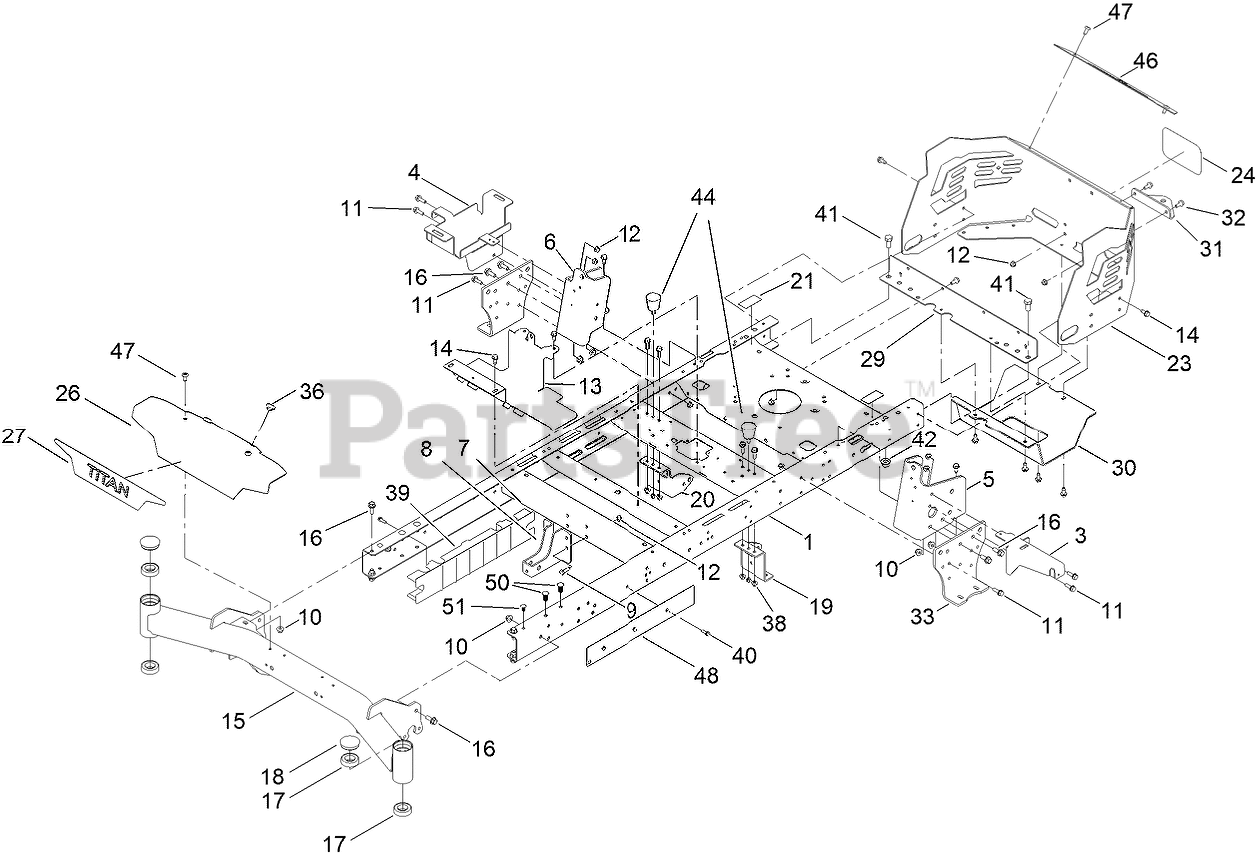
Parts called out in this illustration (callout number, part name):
1	FRAME ASM
3	BRACKET-SUPPORT, POD (LH)
4	TRAY-BATTERY
5	BRACKET-MOUNTING, LH
6	BRACKET-MOUNTING, RH
7	BRACE-CROSS, LOWER
8	BRACKET-MOUNT DAMPER, LOWER
9	SCREW-HH
10	NUT-HF, NI
11	SCREW-HHF
12	NUT-HF
13	BRACKET-MOUNT
14	SCREW-HWHTF
15	FRONT AXLE ASM
16	SCREW-HHF
17	BEARING-BALL
18	CAP-GREASE
19	MOUNT-HYDRO, FRONT (LEFT)
20	MOUNT-HYDRO, FRONT (RIGHT)
21	DECAL-BYPASS
23	GUARD-ENGINE
24	DECAL
26	PLATE-FRONT
27	DECAL-TITAN
29	CROSSMEMBER-REAR, WIDE
30	GUARD-MUFFLER
31	BRACKET-HITCH
32	SCREW-HHF
33	MOUNT-HYDRO
36	BUMPER-SEAT
38	NUT-HEX
39	GUARD-RAIL
40	SCREW-PLASTITE, HWH
41	SCREW-HH
42	NUT-HF
44	BUMPER-RUBBER
46	TRIM-GUARD, ENGINE
48	PLATE-FRAME
50	RIVET-PUSH
51	RIVET-PUSH
